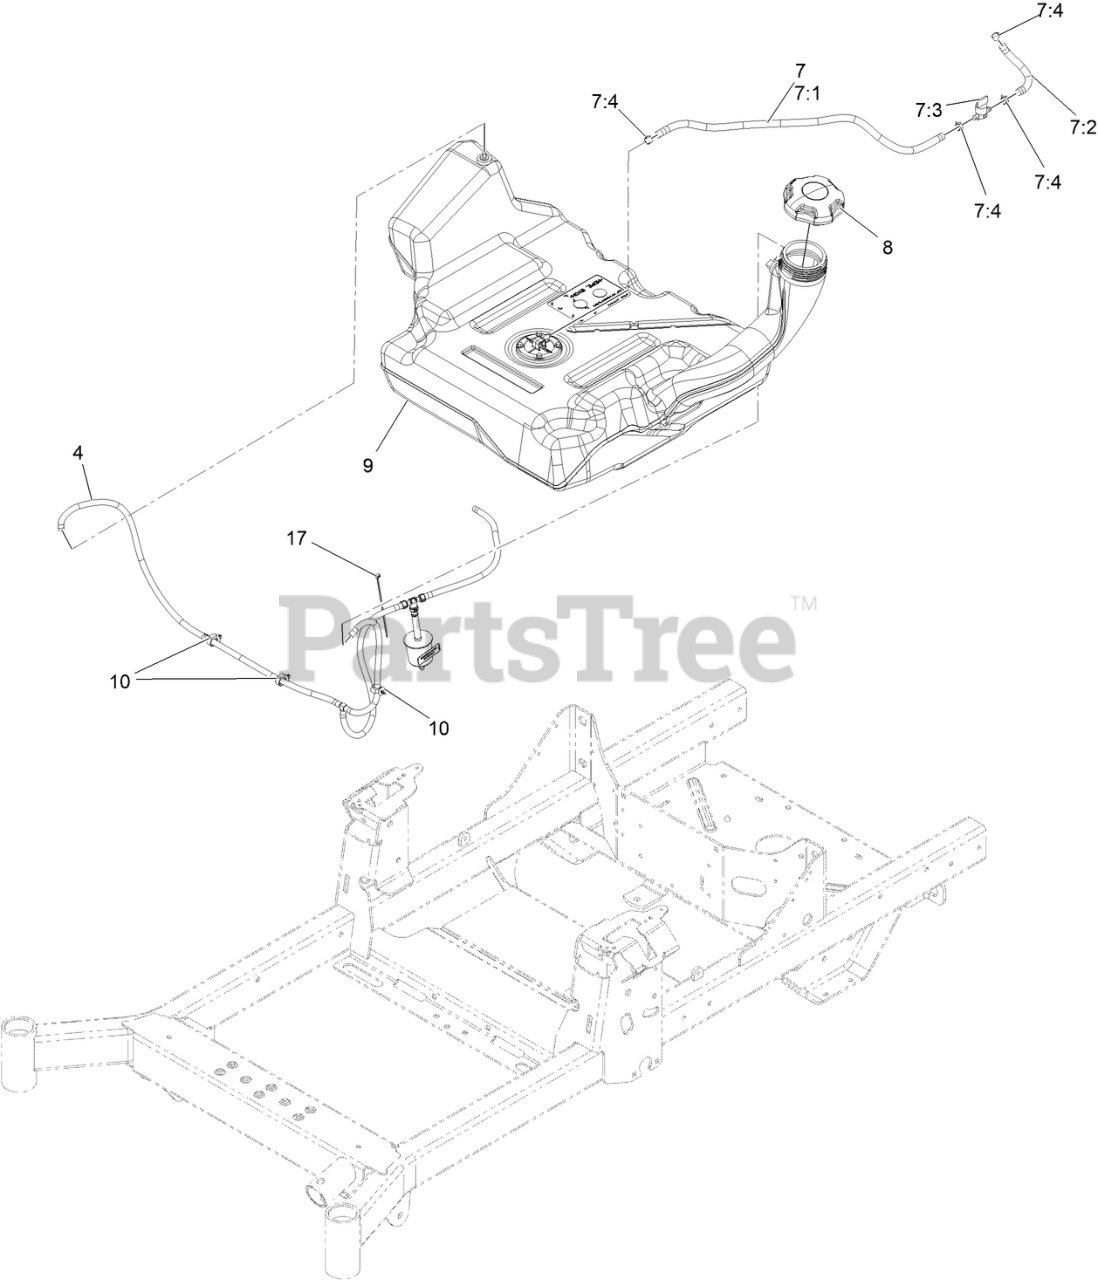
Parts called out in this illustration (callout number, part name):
4	VENT HOSE ASM
7	FUEL HOSE ASM
7:1	HOSE-FUEL
7:2	HOSE-FUEL
7:3	VALVE-FUEL
7:4	CLAMP-HOSE
8	CAP-FUEL, RATCHETING
9	TANK-FUEL
17	TIE-CABLE
